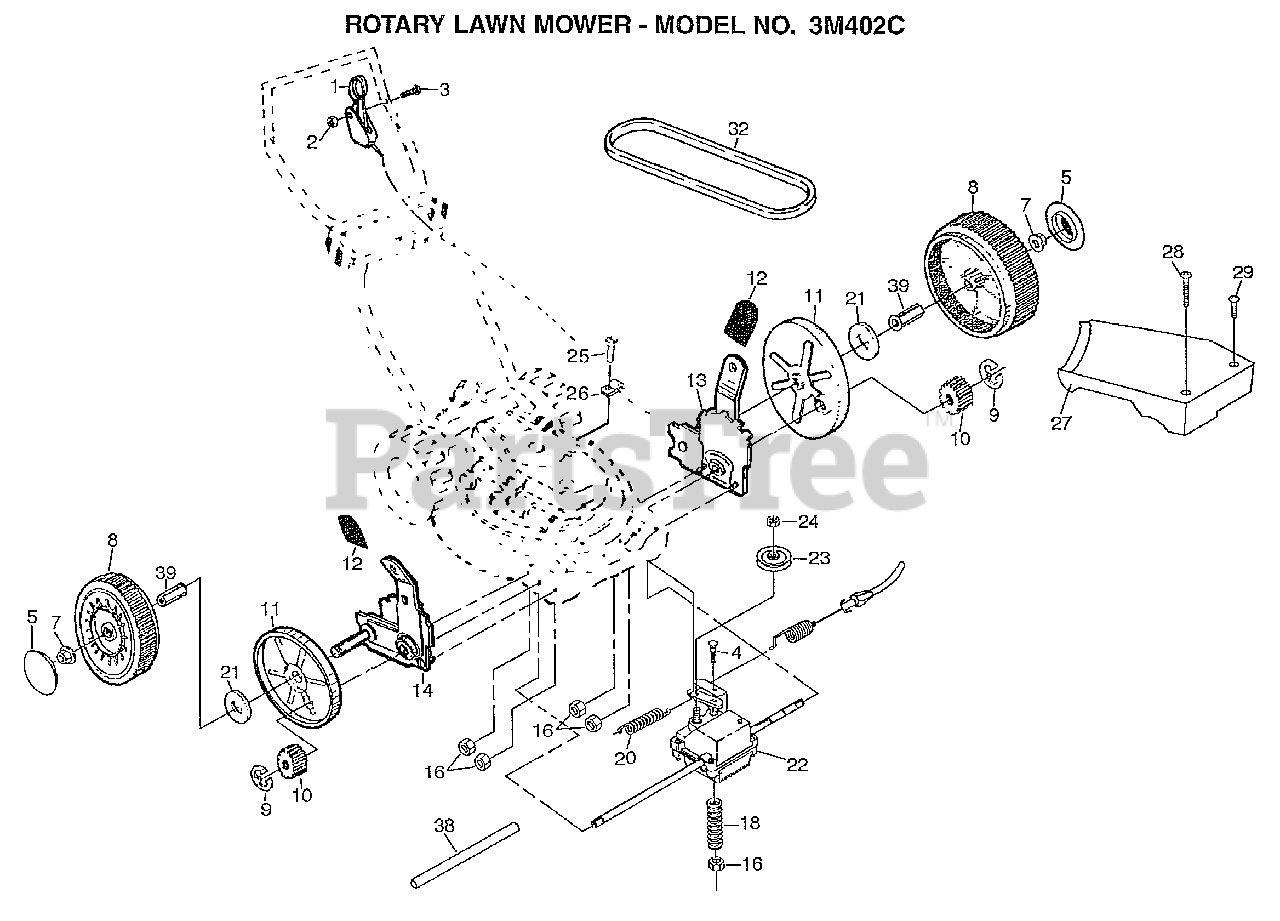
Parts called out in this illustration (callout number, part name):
1	CONTROL.DRV.56.25
3	SCREW.HXHD.WASH.
4	BOLT.1/4-20X2.0
5	HUB CAP
7	NUT.HXFLG.LOCK.
8	WHEEL.8X2.LP.PR
9	E-RING.7/16.RE.
10	PINION.GEAR
11	DUST SHROUD PM
12	KNOB PM
13	WHEEL.ADJ.ASM.LH.
14	WHEEL.ADJ.ASM.RH.
18	SPRING.TENSION
20	SPRING
21	WASHER FLUT
23	PULLEY.DRIVEN
24	LOCKNUT
25	TAPPING SCREW
26	GUIDE CLIP PM
27	COVER DRIVE BLK
28	SCREWL.SLOT.TORXT
29	SCREW.SLOT.TORTX.
38	DRV SHAFT TUBE PM
39	BUSHING.HEX
